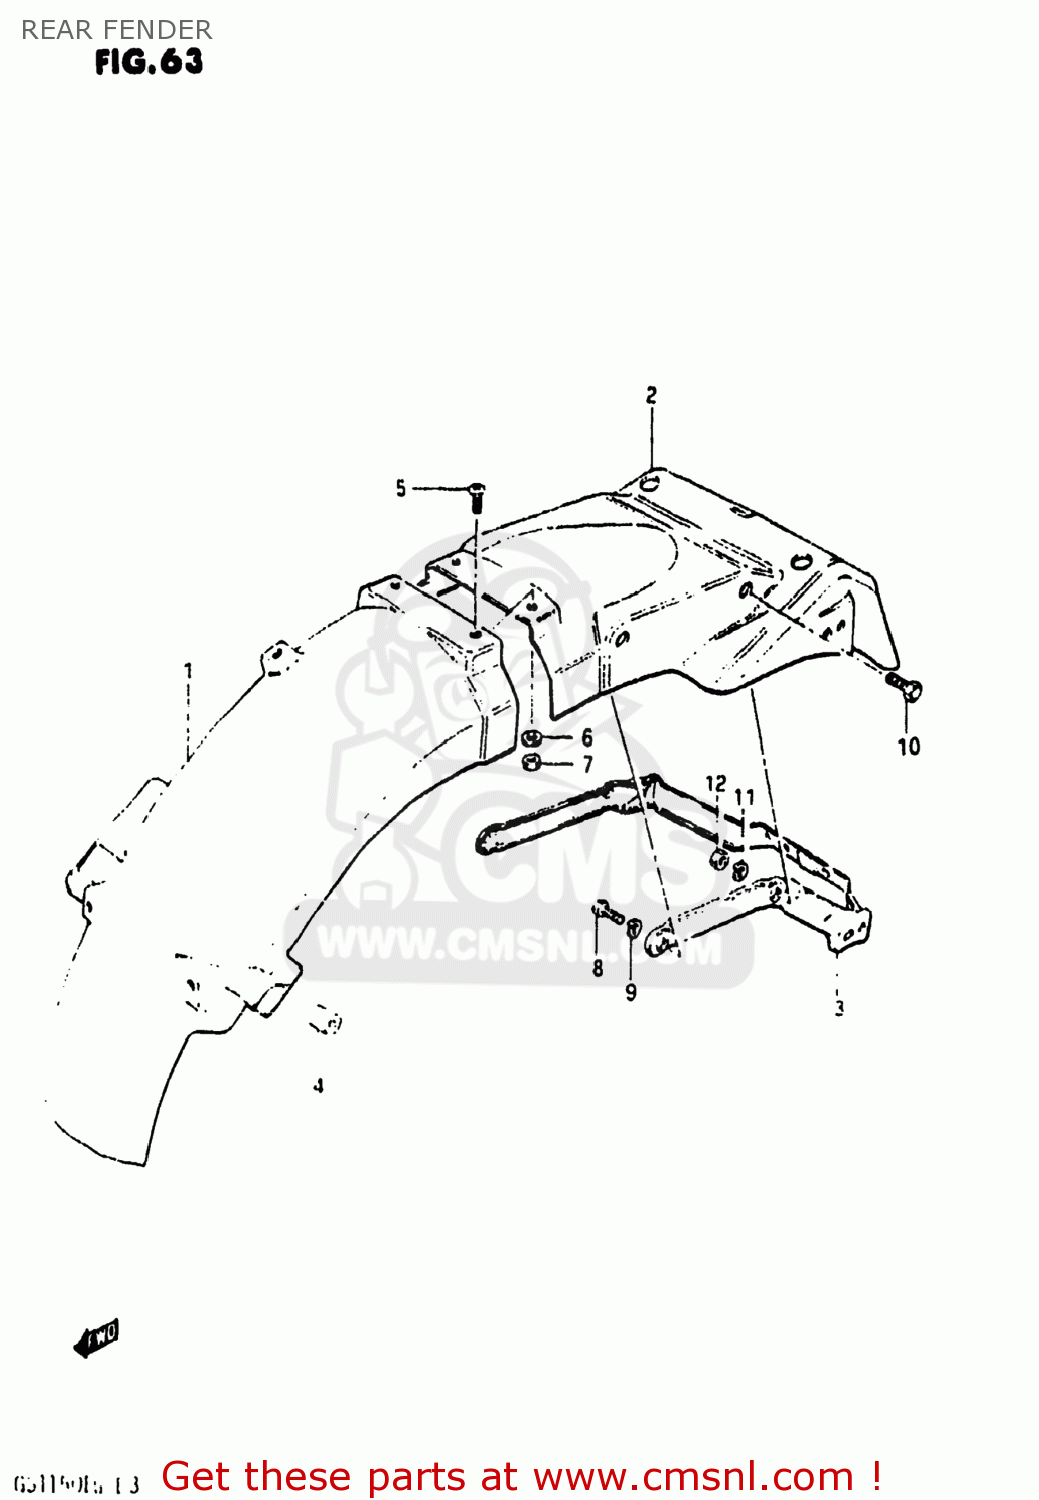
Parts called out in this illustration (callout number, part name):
1	FENDER,REAR
2	BODY,REAR FENDER,REAR
3	REINFORCEMENT,REAR FENDER
4	CUSHION
5	SCREW, FRONT & REAR
6	WASHER (5.5X16X1.2)
7	NUT
8	BOLT
9	WASHER,LOCK
10	BOLT,8X1.25X2
11	WASHER,LOCK,8.
12	NUT
